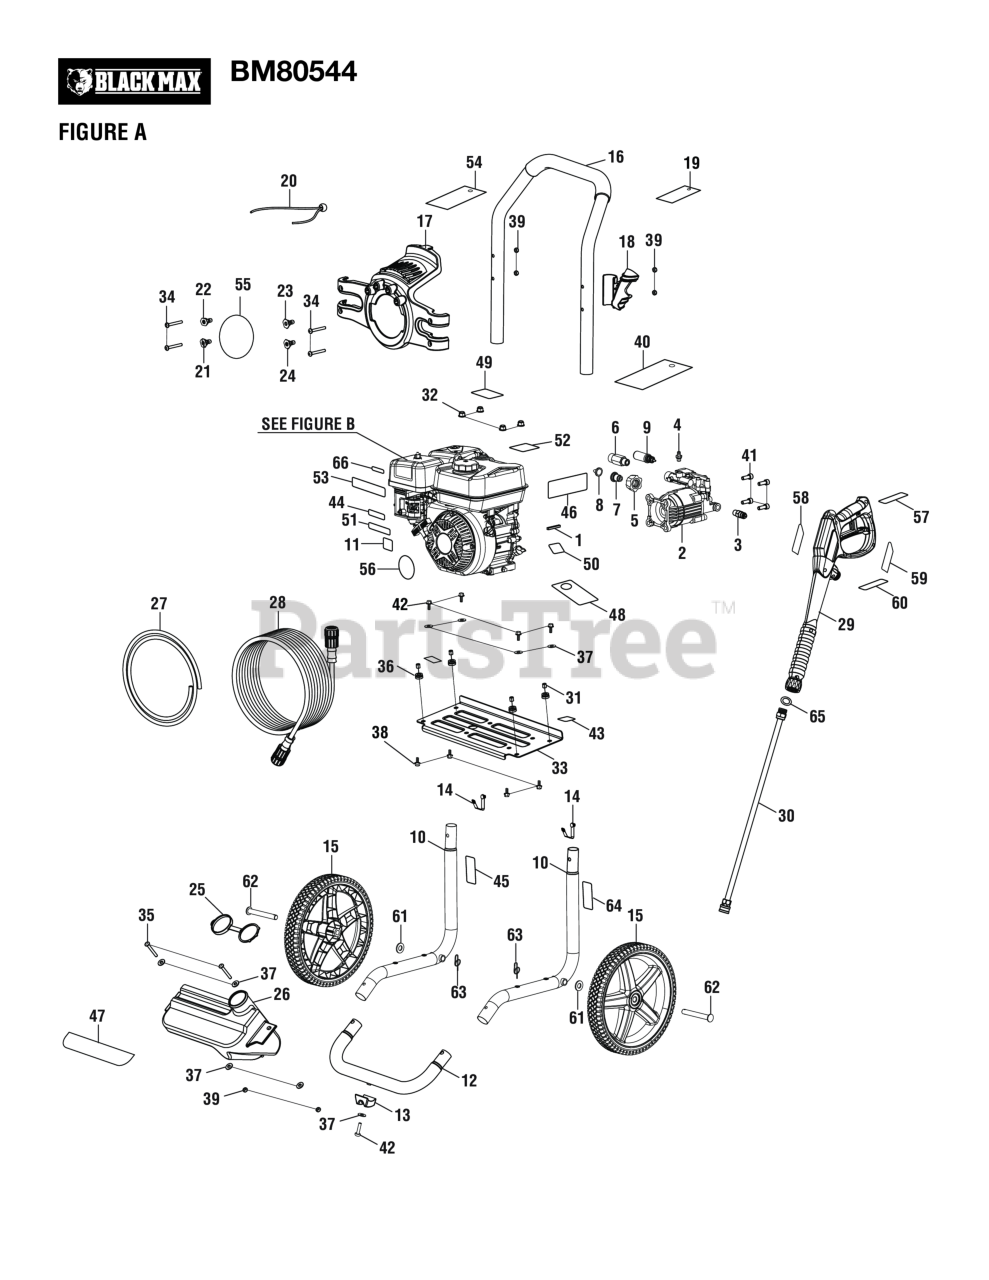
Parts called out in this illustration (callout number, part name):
1	Output Shaft Key (3/16 in. x 40 mm)
2	Pump
3	Thermal Release Valve.
4	Detergent Injector Assembly
5	Inlet Filter Adapter/Brass Insert
6	Outlet Tube
7	Inlet Filter Connector
8	Filter Screen (Pump Inlet)
9	Unloader Valve Assembly
10	Main Frame Assembly
11	Choke/Fuel Valve Label
12	Front Frame Assembly
13	Rubber Foot
14	Lock Button w/Spring Clip.
16	Handle Assembly
17	Hose and Nozzle Holder Assembly
18	Trigger Handle Holder
19	Quick Start Hangtag
20	Bungee Cord and Bead Assembly
21	0deg Nozzle
22	25deg Nozzle
23	40deg Nozzle
24	Soap Nozzle (Blue)
25	Soap Tank Cap
26	Soap Tank
27	Chemical Siphon Tube
28	High Pressure Hose (25 ft.)
29	Trigger Handle
30	Extension Wand
31	Spacer (Fuel Tank Isolator)
32	Lock Nut (M8 x 1.25 mm, Flange)
33	Engine Plate
34	Bolt (M6 x 48 mm, Button Hd.)
35	Screw (M6 x 1 x 48 mm, T30 Torx Pan Hd.)
36	Bushing (Fuel Tank Isolator)
37	Washer (1/4 in.)
38	Bolt (M8 x 36 mm, Hex Flange Hd.)
39	Lock Nut (M6 x 1)
40	Danger Hang Tag
41	Screw (5/16-24 x 23 mm, Hex Soc. Cap Hd.)
42	Screw (M6 x 1.25in., T30 Torx Pan Hd.)
43	Oil Fill Location Label
44	Choke Label
45	Combustion Label (English/Spanish)
46	Danger Label
47	Detergent Tank Label
48	Label (Oil Dipstick Hangtag)
49	No E85 Label
50	Engine Switch Label
51	Fuel Valve Label
52	Hot Surface and Exhaust Label
53	Label (Inquiries Blackmax)
54	Nozzle Instructions Hangtag
55	Performance Label
56	Recoil Label
57	Label (Trigger Handle Warning, French & Spanish)
58	Trigger Handle Warning Label (English)
59	Rating Label
60	Trigger Handle Logo Label
61	Washer (1/2 in.)
63	Hitch Pin
64	Data Warnings Label (English/Spanish)
65	O-Ring (9.5 x 2.65, NBR Shore A 90)
66	EMC ICES-2/NMB-2 Label (Canada)
